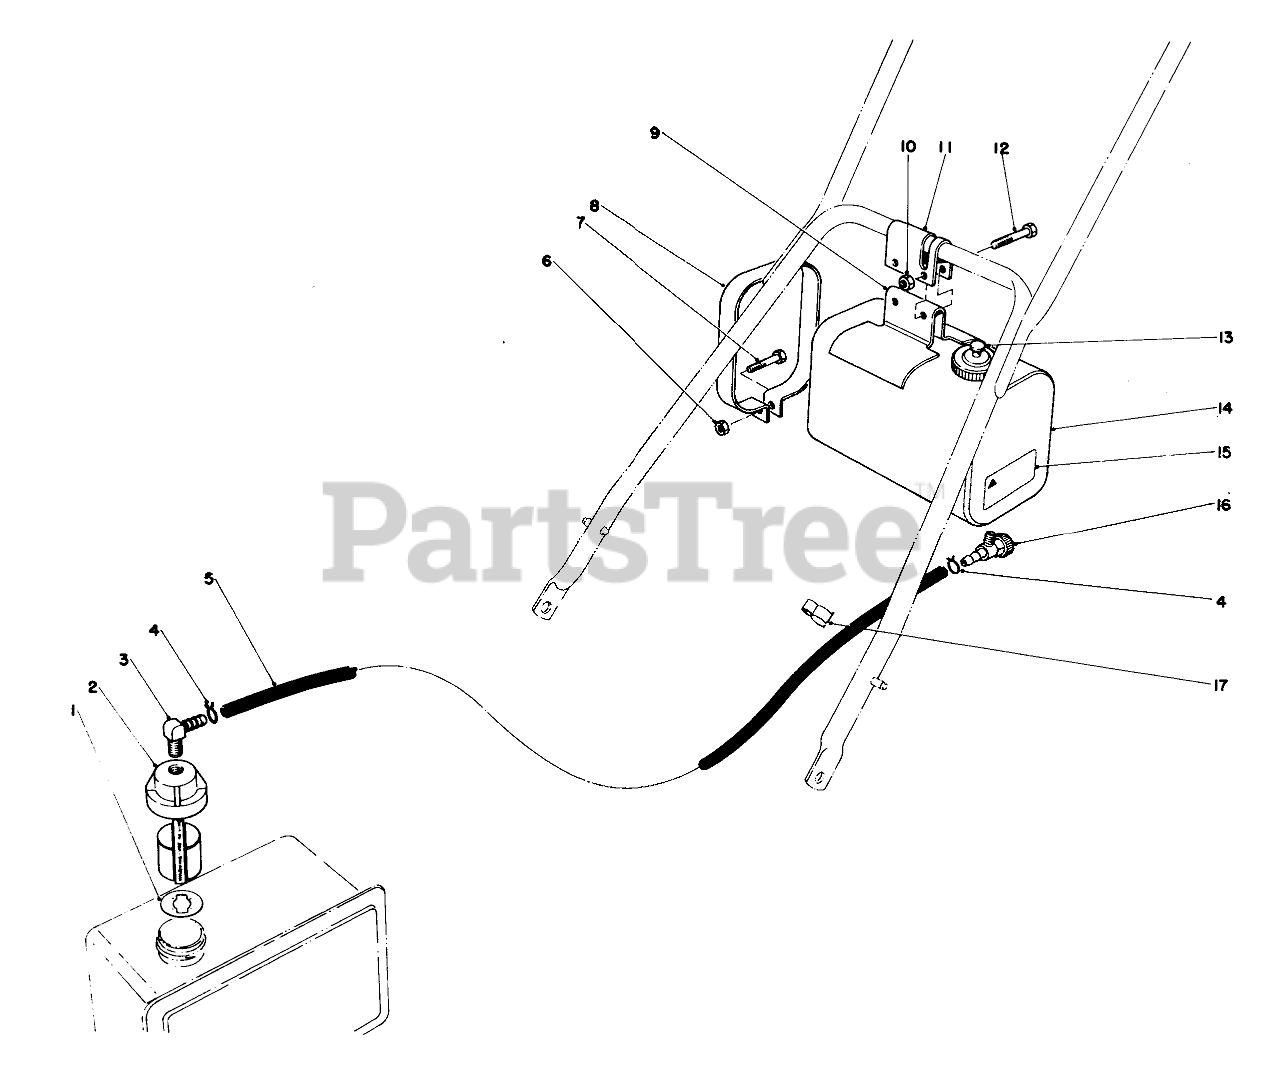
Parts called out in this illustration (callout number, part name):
1	GASKET
2	Fuel Control Valve (Incl. Ref.#1)
3	CONNECTOR-HOSE
4	Clamp
5	FUEL LINE
6	NUT-LOCK
7	SCREW-HH
8	TANK STRAP
9	FUEL TANK BRACKET
10	Nut
11	Clamp
12	SCREW-HH
14	Fuel Tank (Incl. Ref. #13)
15	Decal-Caution
16	.125 ID SHUTOFF VALVE
17	CLAMP
